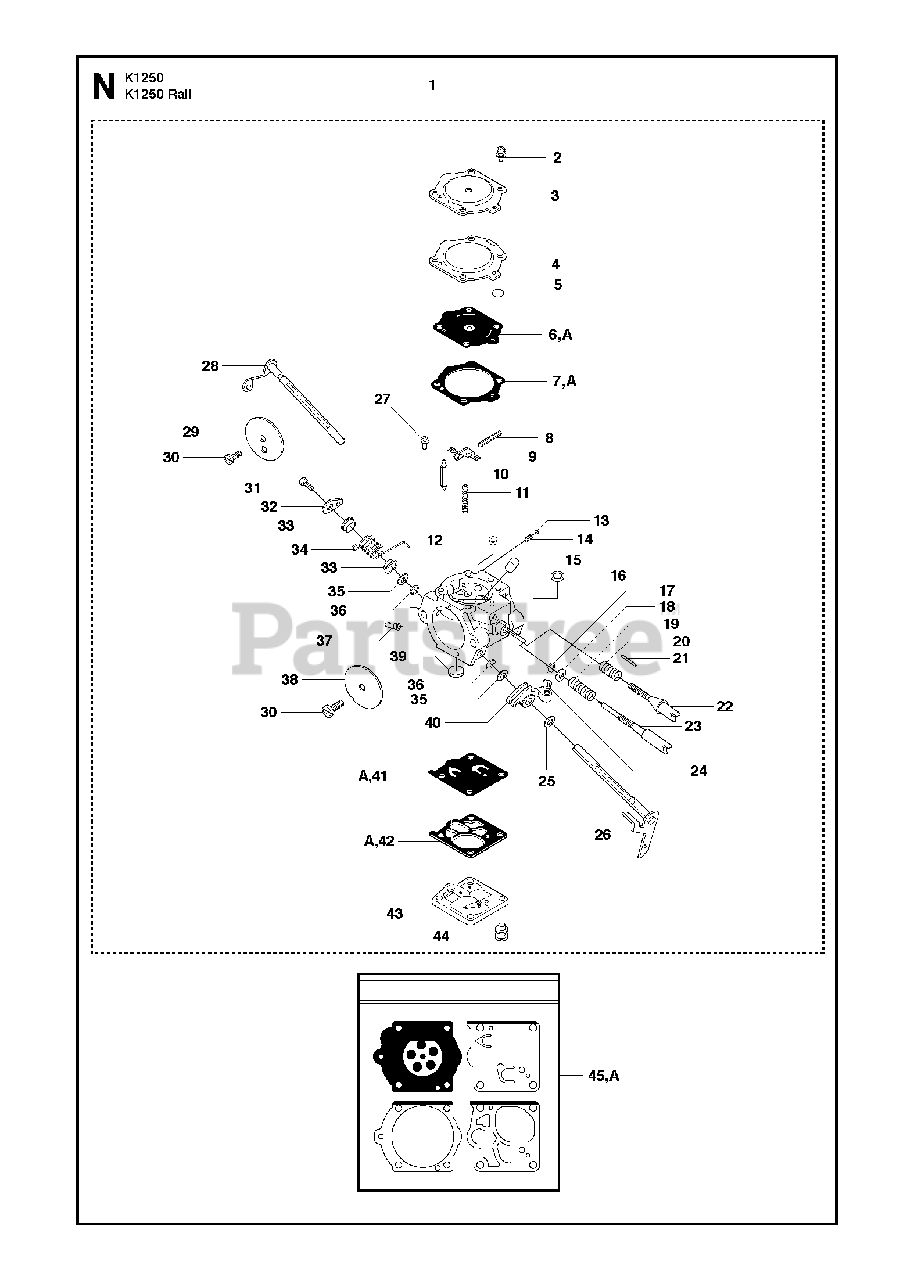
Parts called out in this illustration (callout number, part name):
1	CARBURETTOR
6	DIAPHRAGM ASSYKit 45
7	GASKETKit 45
8	PIN-METERING LEVER
21	PIN THROTTLE STOP
22	SCREW IDLE SPEED
23	NEEDLE IDLE SPEED
31	SCREW PAN HD(M2.5X5)
34	SPRING THROTT RETURN
38	VALVE THROTTLE
41	DIAPHRAGM PUMPKit 45
42	GASKETKit 45
